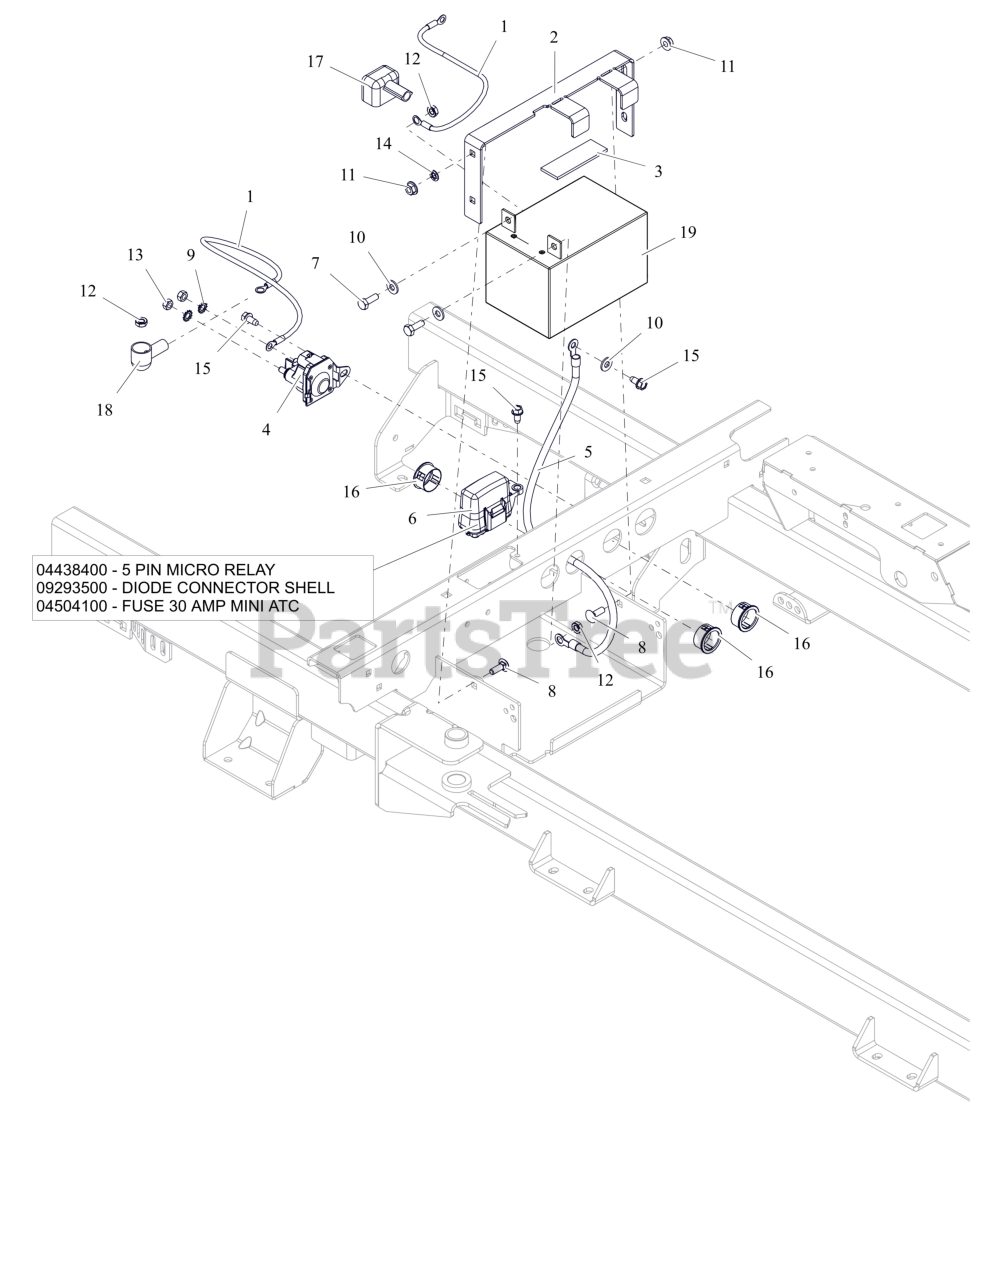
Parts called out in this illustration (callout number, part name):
1	CABLE,POS W/2 1/4 RING 15.0 LG
2	BRKT, BATTERY HOLD-DOWN (BLACK)
3	PAD,RBR 1.0"X3.0" W/ADHESIVE
4	SOLENOID, STARTER (SEALED)
5	CABLE-NEGATIVE BATTERY 24.00"
6	HARNESS, WIRE
6	RELAY,MICRO5 TERML W/RESISTOR
6	DIODE, CONNECTOR SHELL
6	FUSE,30 AMP MINI-ATC
7	BLT, HEX .25-20X.75 G5 ZCC
8	BLT, RHSN .25-20X.750 G5 ZCC
9	WSHR,LK-EXT.262X.502X.026 ZCC
10	WSHR,FLT .281X.625X.065 ZCC
11	NUT-LK-TOP-FLG .250-20 GF ZCC
12	NUT-KEPS .250-20 ZCC
13	NUT-STD M6-1.0 ZCC
14	NUT-PUSH .25X.50 O.D.
15	SCR-TAP .25-20X.50 HWH ZCC
16	BSHG, PANEL SNAP .937X1.11X.56
17	INSULATOR
18	BOOT, EYELET TERMINAL
19	BATTERY, 12V 12A -190CCA
